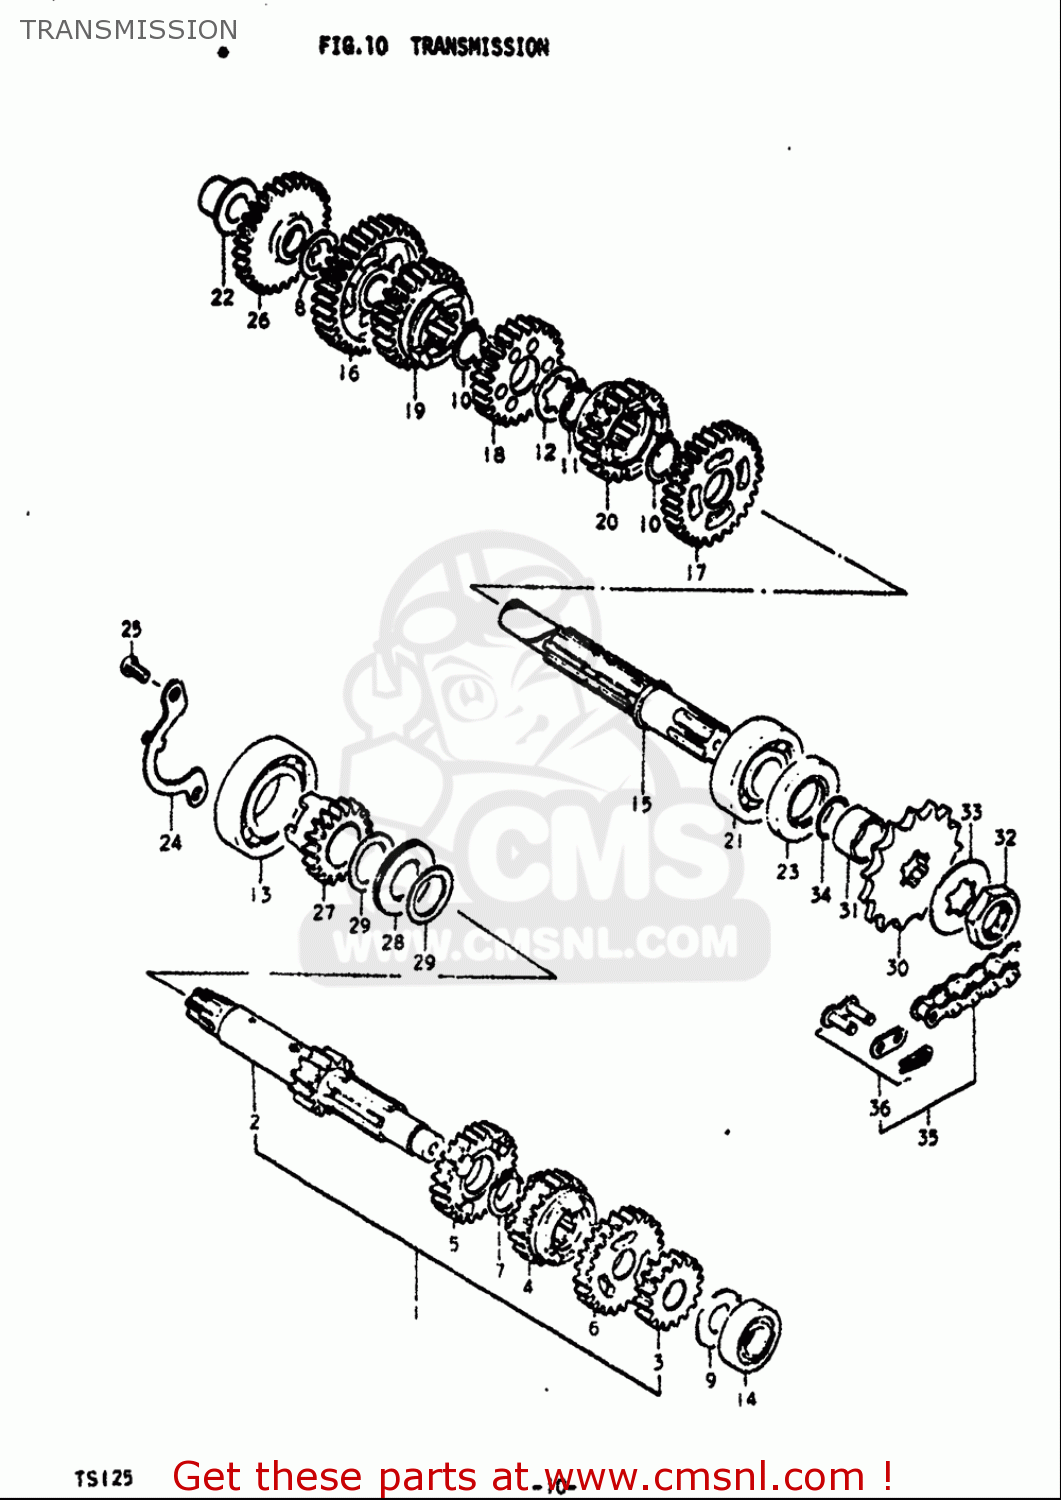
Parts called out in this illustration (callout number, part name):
3	GEAR,2ND DRIVE
4	GEAR,THIRD DRIVE
5	GEAR,4TH DRIVE
7	CIRCLIP
8	SHIM, 15X24X1.0
9	WASHER
10	CIRCLIP
11	CIRCLIP
12	WASHER,LOCK
13	BEARING
14	BEARING
15	SHAFT,DRIVE
16	GEAR,1ST DRIVEN
17	GEAR,2ND DRIVEN
18	GEAR,3RD DRIVEN
19	GEAR,4TH DRIVEN
20	GEAR,5TH DRIVEN
21	BEARING
22	BUSH
23	OIL SEAL (25X44X7)
24	RETAINER,CNTR SHAFT BEARING
25	SCREW
27	GEAR,KICK STARTER DRIVEN
28	BEARING(21X32X2.85)
29	WASHER(21X30X0.8)
30	SPROCKET,ENGINE(NT:15)
31	SPACER(20X25X12.5)
32	NUT
33	WASHER,LOCK
34	O RING(D:1,ID:19.5)
35	CHAIN,DRIVE
